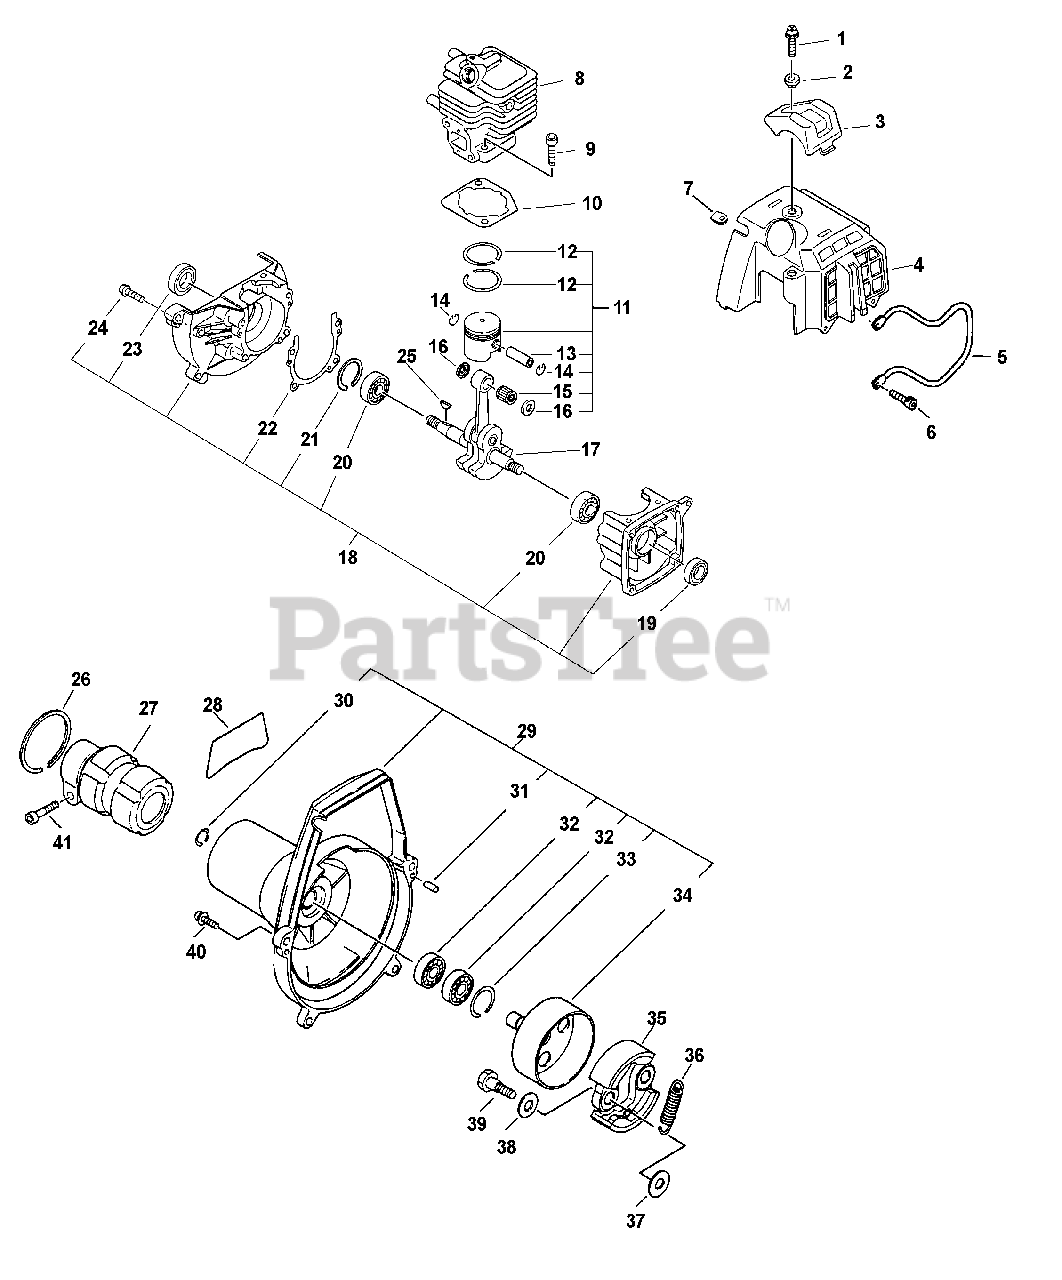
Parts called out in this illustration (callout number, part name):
1	SCREW 5×22
2	COLLAR 5
3	GUARD, TOP
4	COVER, CYLINDER
5	GUARD, ENGINE
6	BOLT 4×16
7	GROMMET, PLUG
8	CYLINDER
9	BOLT 5×22
10	GASKET, CYLINDER
11	PISTON KIT
12	RING, PISTON
13	PIN, PISTON
14	RING, SNAP
15	BEARING, NEEDLE
16	WASHER, THRUST
17	CRANKSHAFT ASSY
18	CRANKCASE KIT
19	SEAL, OIL 12
20	BEARING, BALL 6001
21	RING, SNAP 28
22	GASKET, CRANKCASE
23	SEAL, OIL 12
24	BOLT 5×25
25	KEY, WOODRUFF
26	RING, SNAP Ø42
27	HOLDER, MAIN PIPE
28	LABEL, MODEL
29	FAN CASE ASSY
30	RING, RETAINING - 12
31	PIN, LOCATING 4
32	BEARING, BALL 6001
33	RING, SNAP 28
34	DRUM, CLUTCH
35	SHOE, CLUTCH
36	SPRING, CLUTCH
37	WASHER 6.2×19×1.0
38	WASHER, SPRING 8.5×16×0.5
39	BOLT, CLUTCH 8×7.9×M6
40	BOLT 5×18
41	BOLT 5×28
